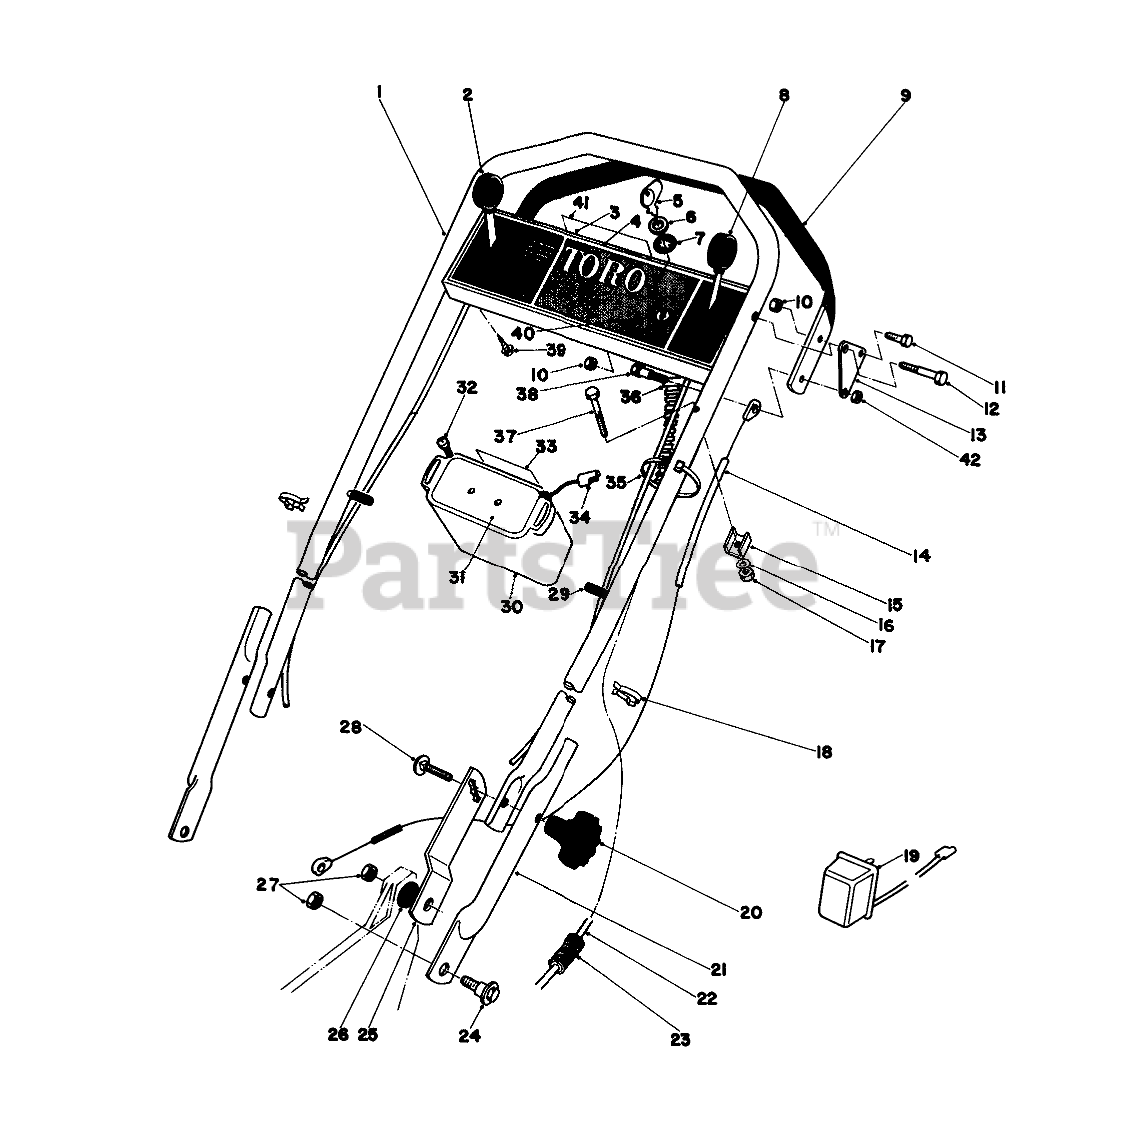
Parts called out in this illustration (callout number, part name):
1	Upper Handle
2	GROUND SPEED CONTROL
3	Control Panel
4	Decal-Key Lectric
5	Key
6	NUT-HH
7	WASHER-TOOTH, INTERNAL
8	Throttle Control
9	DEMAND HANDLE ASM
10	NUT-LOCK, CONE
11	SCREW-HH
12	BOLT-SHOULDER
13	Bracket Demand
14	DEMAND HAND CABLE
15	CLAMP-CABLE
16	WASHER-FLAT
17	NUT-LOCK, NI
18	BOWDEN CLIP
19	Charger
21	LOWER HANDLE
22	WIRE HARNESS
23	Cover-Wiring Harness
24	SCREW-SHOULDER
25	Handle Latch L.H.
26	SPACER
27	Nut
28	SCREW-CARR
29	CAP-VINYL
30	Battery Case
31	BATTERY COVER
33	Decal
34	Plug & Wire
35	TIE-CABLE
36	RING FITTING
37	SCREW-HH
38	Shoulder Bolt
39	SCREW-HWHTF
40	Starter Switch (Incl. Ref. #5-7)
41	Decal-Select-a-Pace
42	NUT-HEX, SIDE DEFORM
